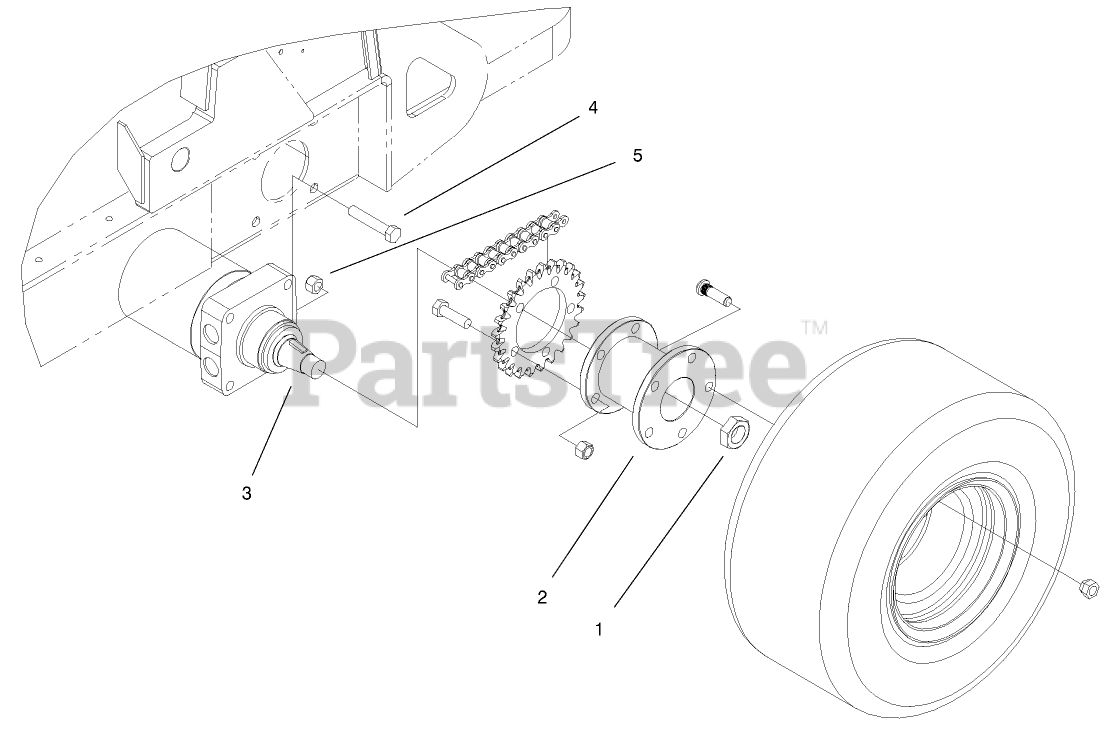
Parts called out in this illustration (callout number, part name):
1	NUT-LOCK
2	HUB - REAR
3	HYDRAULIC MOTOR ASM
5	NUT-LOCK, HEX NI
